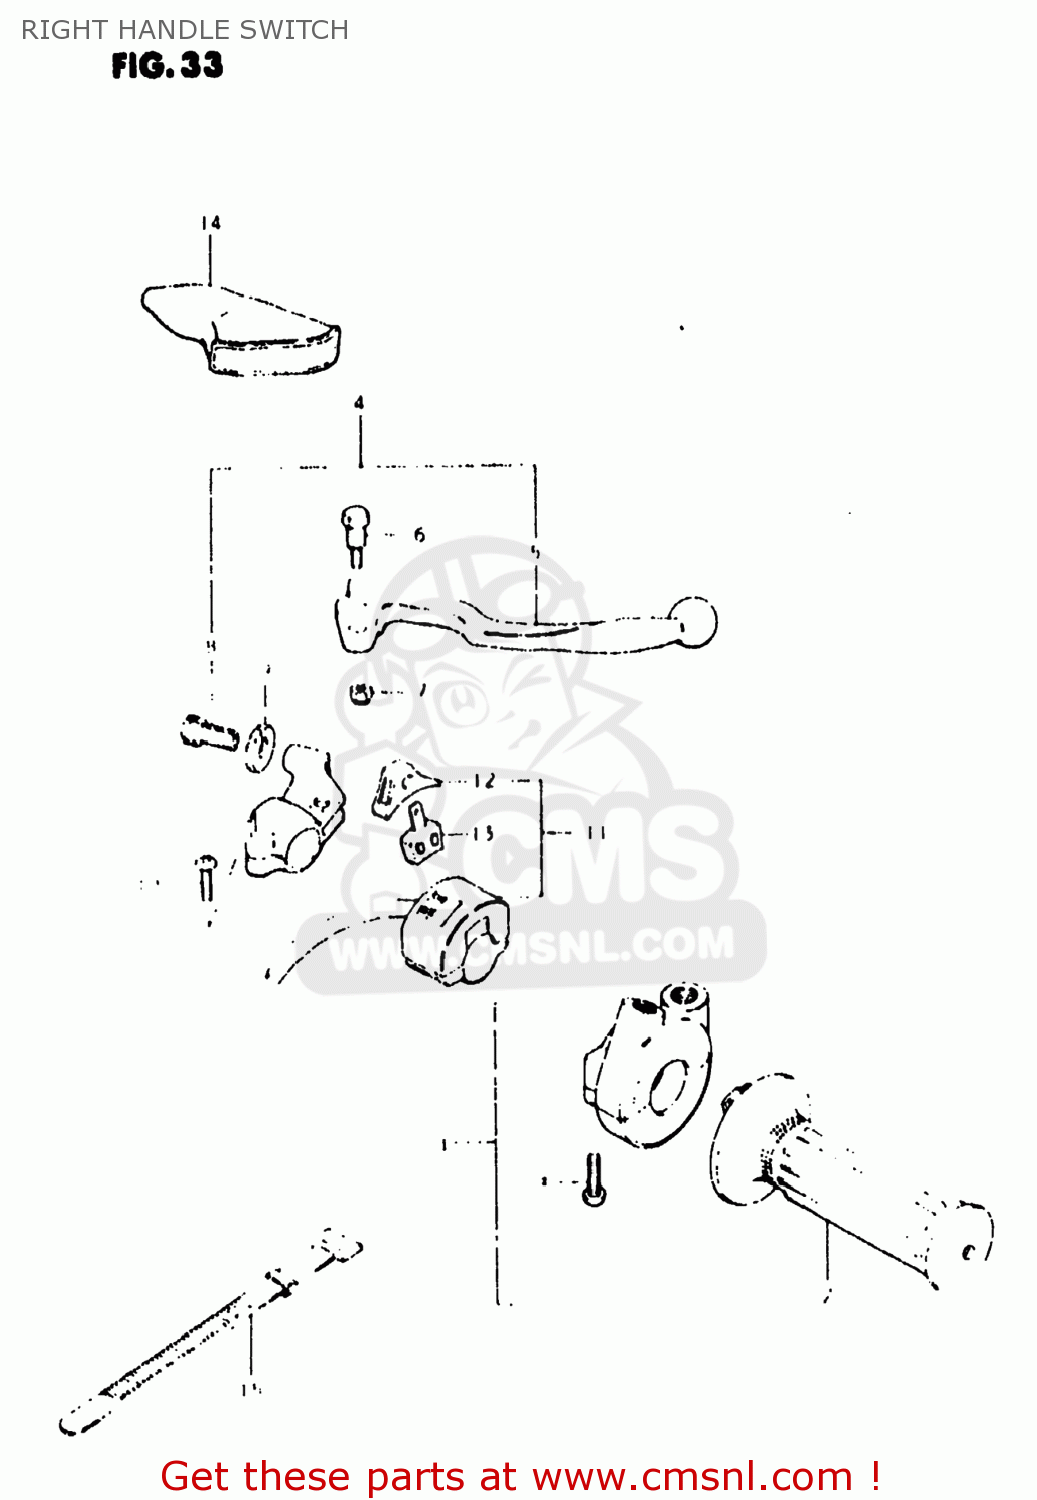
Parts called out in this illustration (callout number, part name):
1	CASE ASSEMBLY,THROTTLE
2	GRIP,THROTTLE
3	SCREW 5X20
4	LEVER ASSEMBLY,BRAKE
5	LEVER,BRAKE
6	BOLT,LEVER
7	NUT 6MM
8	ADJUSTER,CABLE
9	NUT,CABLE ADJUSTER
10	SCREW
11	SWITCH ASSEMBLY,LIGHTING
12	KNOB,LIGHTING & DIMMER
13	BLOCK,LIGHTING/DIMMER
14	COVER,CLUTCH LEVER
15	CLAMP(L:120)
